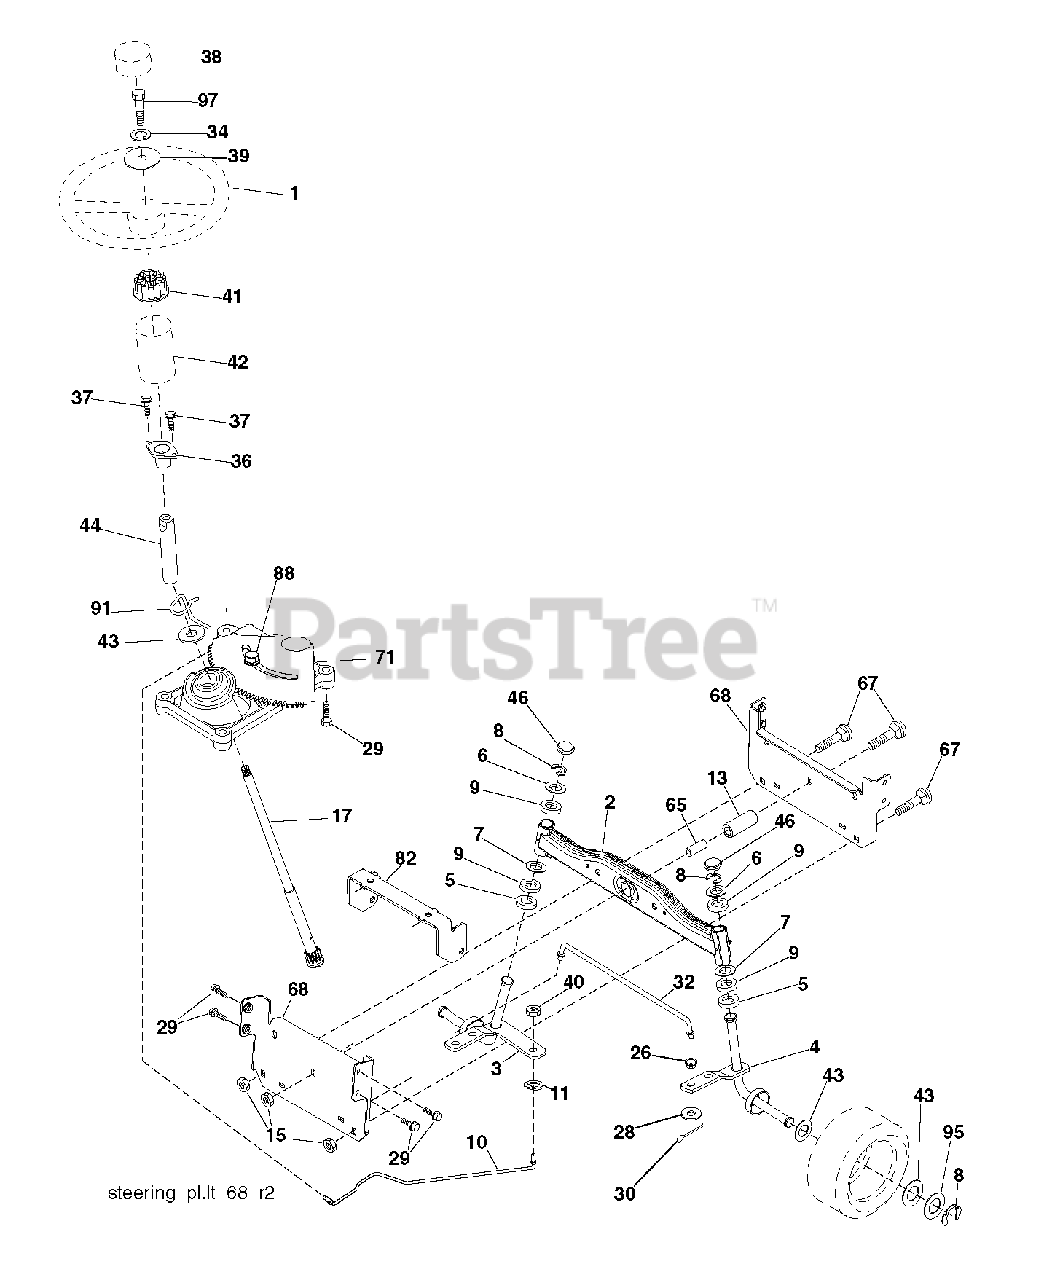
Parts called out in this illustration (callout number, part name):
2	AXLE HALF ASM-WELDED
3	SPINDLE.ASM.LH.15"TIRES
4	SPINDLE.ASM.RH.15"TIRES
8	RING CLIP
9	BRNG T
10	DRAGLINK.15".TIRES.2001
11	WASHER, LOCK 3/8
13	TUBE, PIVOT AXLE
15	NUT LOCK FLG 3/8-16 UNC
17	SHAFT STEERING SPLINE
26	BUSHING.DRAGLINK
28	WASHER
29	SCREW, 3/8-16X3/4
30	COTTER PIN
32	ROD.TIE.WIRE.FORM
34	LOCKWASHER
36	BUSHING, STEERING
39	WASHER.11/32
40	NUT CROWNLOCK 3/8-24
41	ADAPTER, WHEEL STNG..
42	BOOT.STEERING.SHAFT.BLACK
44	SHAFT.EXTEN.STRG.SPLINE
46	CAP.SPINDLE
65	SPACER.BRACE.AXLE
67	BOLT CARRIAGE
68	BRACE.AXLE.15"TIRES
71	STEERING ASM
82	BRACKET.SUSP.CHASSIS.FRONT.15
88	BOLT, SHOULDER 7/16-20
91	CLIP.STEERING
95	WASHER.HARDENED
97	BOLT 5/16-18 X 4 W/PATCH
